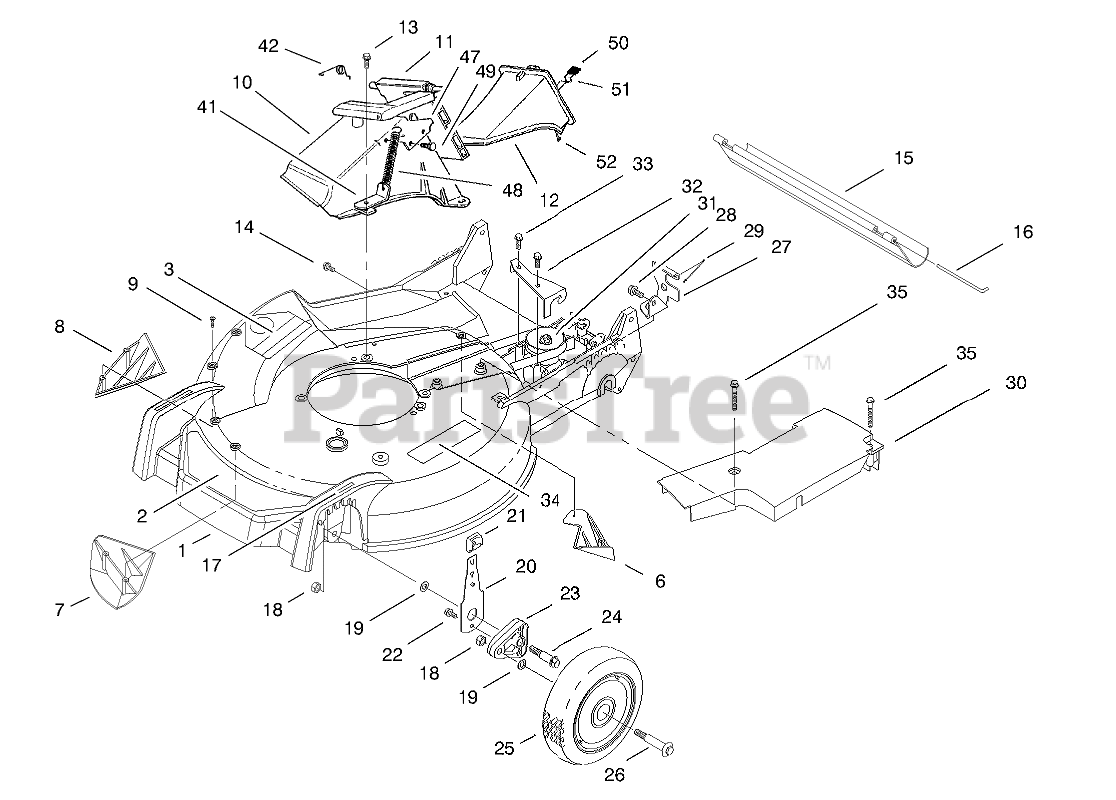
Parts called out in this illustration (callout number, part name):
1	Housing-Rwd (Incl. Ref. #3-9, 17, & 34)
2	DECAL - DECK
3	DECAL-DANGER
6	KICKER-REAR
7	KICKER-FRONT
8	KICKER-RH
9	SCREW-PPH
10	TUNNEL-DISCHARGE
11	DISCHARGE DOOR ASM
12	DISCHARGE PLUG ASM
13	SCREW-HWH
14	SCREW AND WASHER ASM
15	SHIELD-TRAILING
16	ROD-SHIELD
17	DECAL - HOC
18	NUT-LOCK
19	WASHER
20	FRONT SPRING ARM ASM
21	KNOB-ARM
22	SCREW-HWH
23	ARM-PIVOT, FRONT
24	BOLT-SHOULDER
25	ASM-Wheel & Tire (Incl. Ref. #53)
26	BOLT-WHEEL
27	Bracket-Adj. Trac
28	SCREW-HWHTF
29	RETAINER-CABLE
30	COVER - BELT
31	GEARCASE ASM
32	Bracket-Guide
33	SCREW-HWHTF
34	DECAL-WARNING
35	SCREW-HHFTF
41	BRACKET-SPRING
42	RETAINER-DOOR
47	LATCH-PLATE
48	SPRING-DOOR
49	SCREW-PLASTITE
50	GRIP-LATCH
51	LATCH-PLUG, DISCHARGE
52	RIVET-HEAD, FLAT
53	BUSHING
